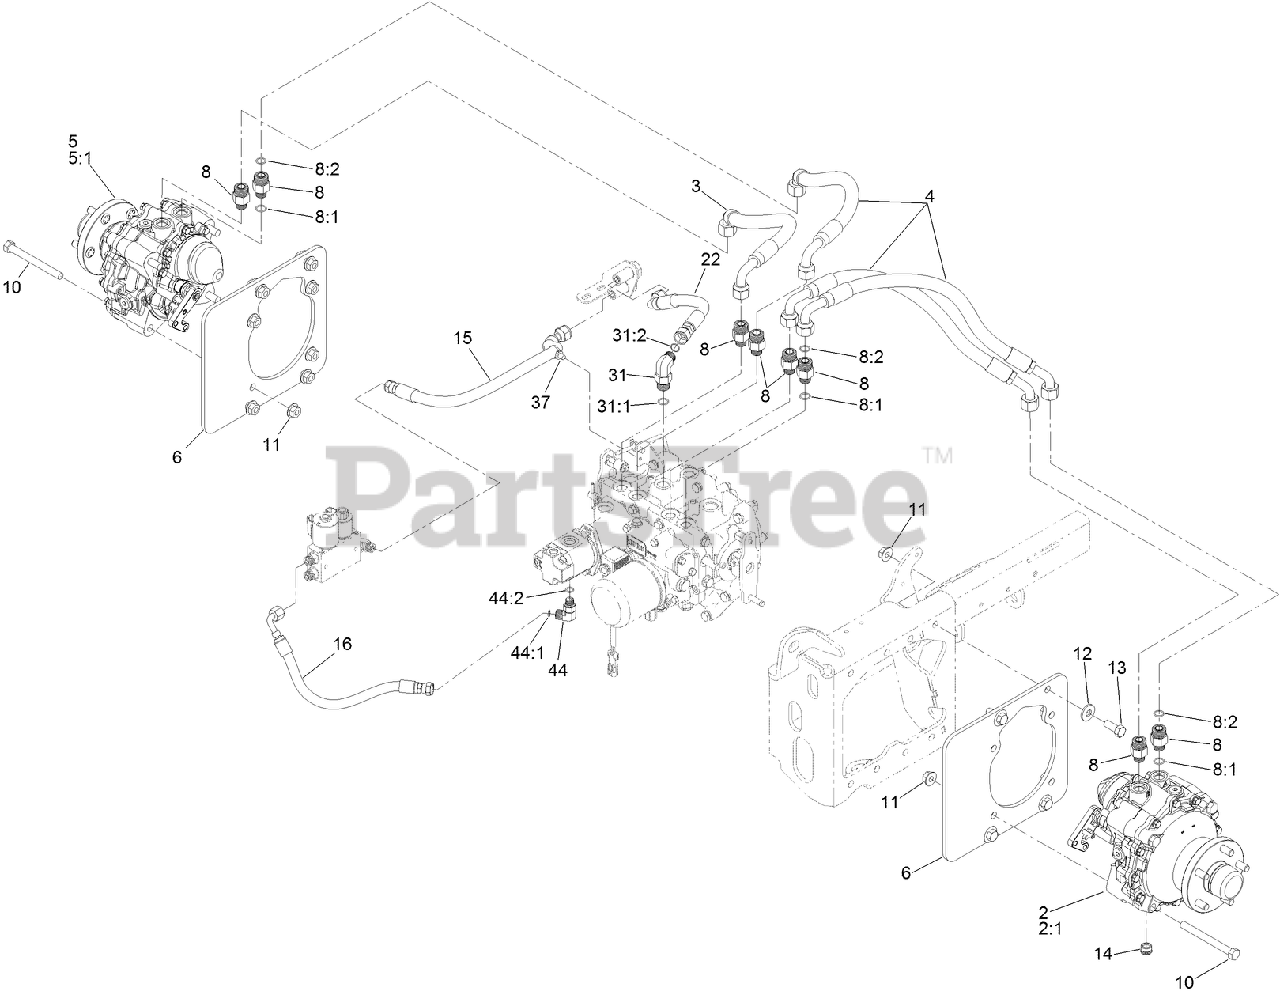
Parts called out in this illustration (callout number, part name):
2	MOTOR-HYD, LH
2:1	5 STUD WHEEL HUB KIT
3	HOSE ASM
4	HOSE ASM
5	MOTOR-HYD, RH
5:1	5 STUD WHEEL HUB KIT
6	PLATE-MOTOR
8	FITTING-STRAIGHT
8:1	O-RING
8:2	O-RING
10	SCREW-HH
11	NUT-HHF
12	WASHER-SPRING
13	SCREW-HH
14	PLUG-MAGNETIC
15	HOSE ASM
16	HOSE ASM
22	HOSE ASM
31	FITTING-ELBOW, 90 DEG
31:1	O-RING
31:2	O-RING
37	CLIP-TIE
44	FITTING-ELBOW, 90 DEG
44:1	O-RING
44:2	O-RING
